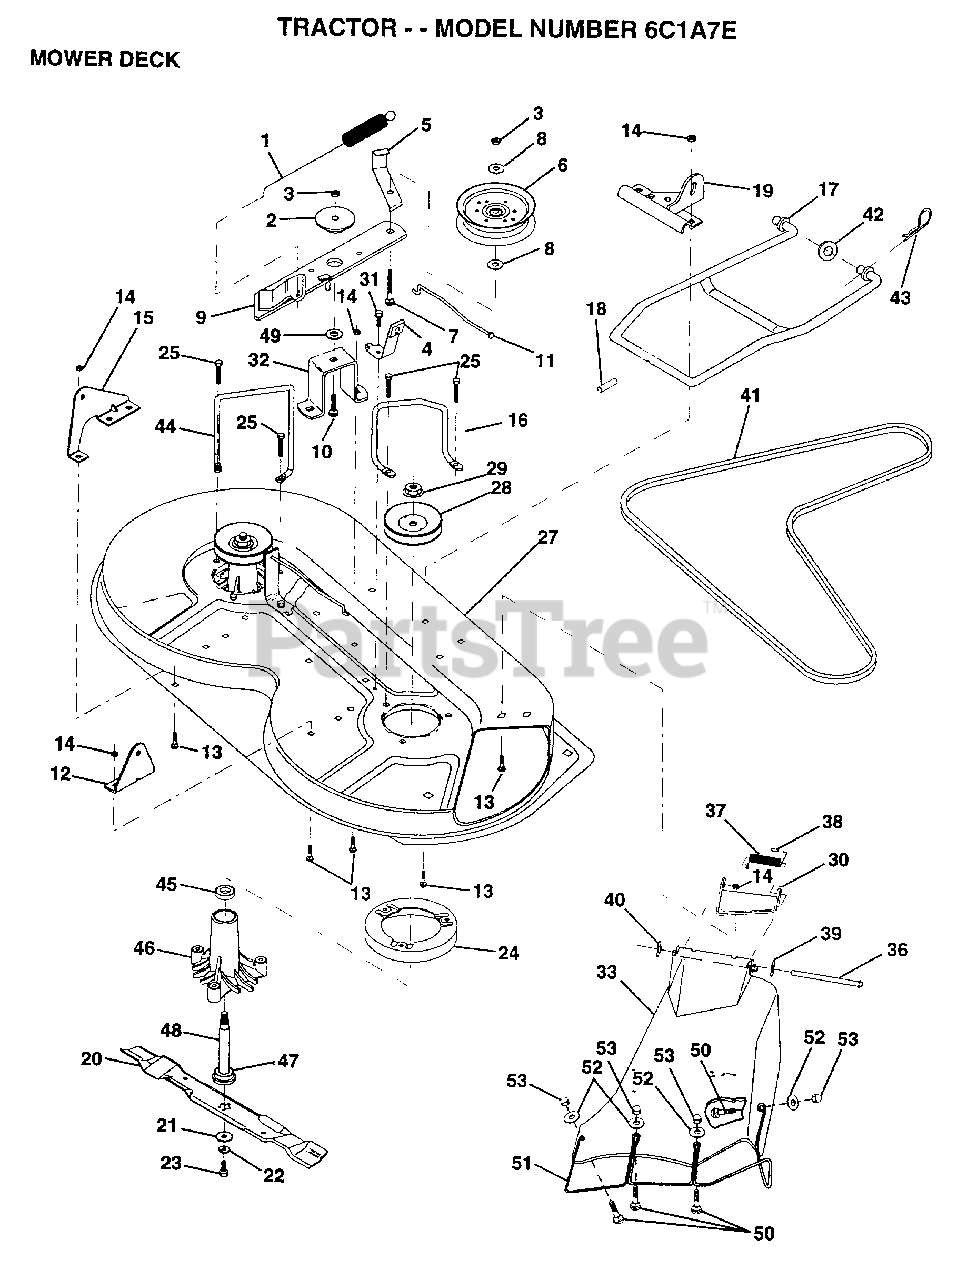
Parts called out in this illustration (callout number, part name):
1	SPRING CLUTCH MWR
2	SPACER RETAINER
4	BRAKE ASM
5	IDLER BELT GUIDE
6	PULLEY IDLER
7	BOLT
8	WASHER
10	BOLT.3/8-14X1.25
11	BRAKE ROD
12	"BRKT,LIFT REAR"
13	BOLT
15	"BRKT,LIFT REAR LH"
16	"KEEPER-BELT,RH"
17	MOWER LINK STAB
18	"PIN,GROOVE"
19	"BRKT,LINK STABILI"
20	"BLADE.36"" HIPERF"
21	WASHER.HARD.BLADE
23	BLADE BOLT
24	STRIPPER RND MWR
28	PULLEY.MAND.36/46
31	SCREW LT
32	"SUPT,IDLER ARM"
33	SHIELD.DEFL.36TUV
36	HINGE ROD
37	SPRING TORSION
38	CAP-SLEEVE LT
39	WASHER
40	NUT PUSH M
41	V-BELT.PRIM.78.5.
43	RETAINER.SPRING
44	KEEPER BELT LH
45	BEARING
46	HSG ASM MANDREL
47	BEARING.BALL
49	HARDENED WASHER
50	SCREW
51	GUARD.DFTR.MWR.36
53	ACORN NUT RB
